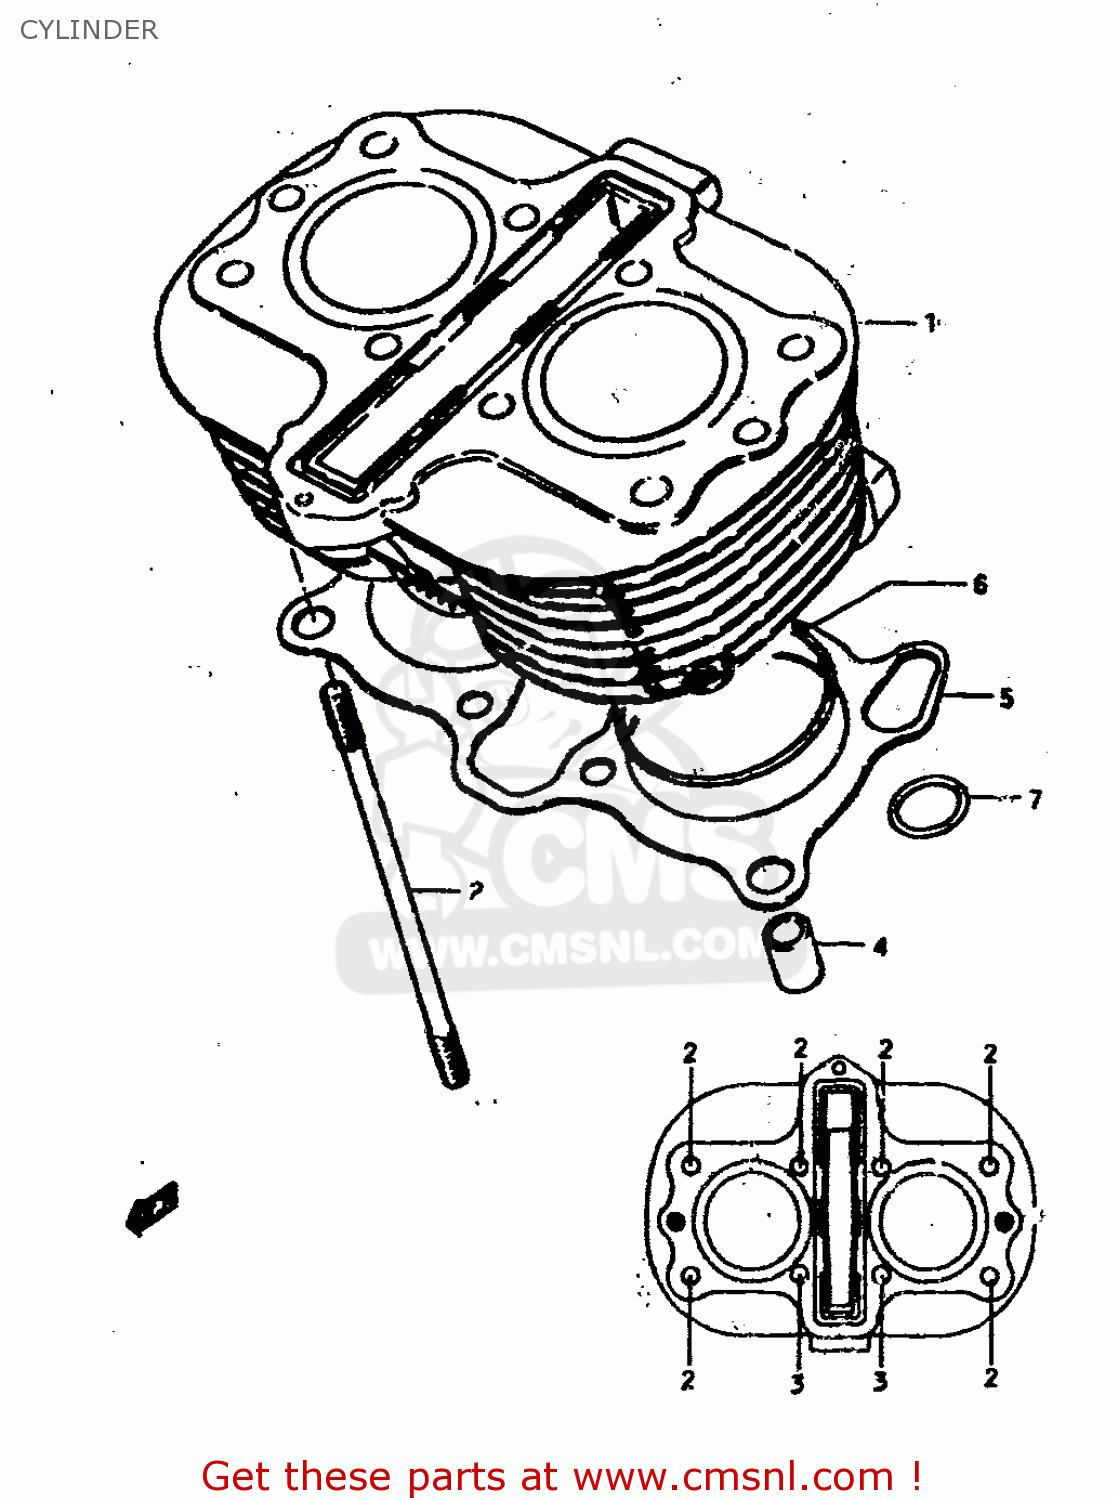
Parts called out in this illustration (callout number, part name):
1	CYLINDER
2	STUD
4	PIN
5	GASKET,CYLINDER (MCA)
6	O RING(D:2,ID:70)
7	O RING(D:3.05)
